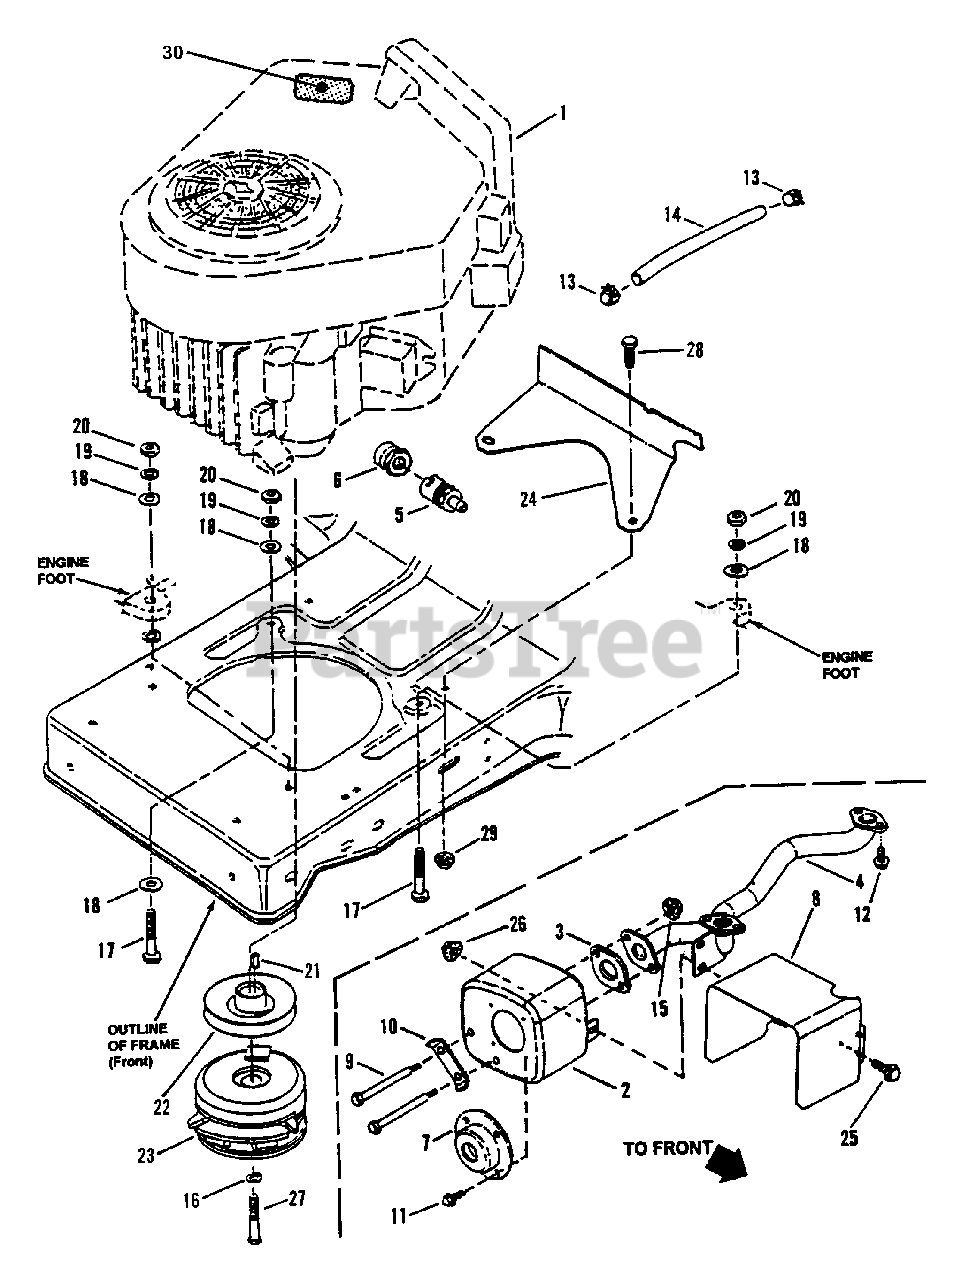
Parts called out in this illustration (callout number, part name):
2	MUFFLER
3	GASKET, Muffler/Exhaust
4	MANIFOLD, Exhaust
5	ASSEMBLY, Oil Valve Drain
6	EXTENSION, Oil Drain
7	DEFLECTOR, Exhaust
8	SHIELD, Muffler Heat
9	BOLT, 5/16-18 x 3-1/2" Shoulder, Hex Head
10	LOCK, Screw
11	SCREW, #8-18 x 1/2" Self-Tapping
12	SCREW, 5/16-18 x 1/2" Hex Washer Head, Self Tapping
13	CLAMP, Fuel Line
14	LINE, Fuel, 14" Long
15	NUT, 5/16-18 Hex Flanged Lock, Grade 5
16	WASHER, 7/16" Split Lock
17	SCREW, 5/16-18 x 1-3/4" Hex Head Cap, Grade 5
18	WASHER, 5/16 Flat Grade 5
19	WASHER, 5/16 Split Lock
20	NUT, 5/16-18 Hex Grade 5 or B
21	KEY, 1/4 x 1/4 x 3/4" Square
22	PULLEY, Traction Drive
23	CLUTCH/BRAKE
24	SHIELD, Heat
25	SCREW, 1/4-20 x 5/8" Hex Head Cap, Grade 5
26	NUT, 1/4 -20 Hex Flanged Lock, Grade 5
27	SCREW, 7/16-20 x 2-1/2 Hex Head Cap, Special, Grade 5
28	SCREW, 5/16-18 x 1" Hex Head Cap, Grade 2
29	NUT, 5/16-18 Hex Flange Lock, Grade 5
30	DECAL, Warning Speed Setting
